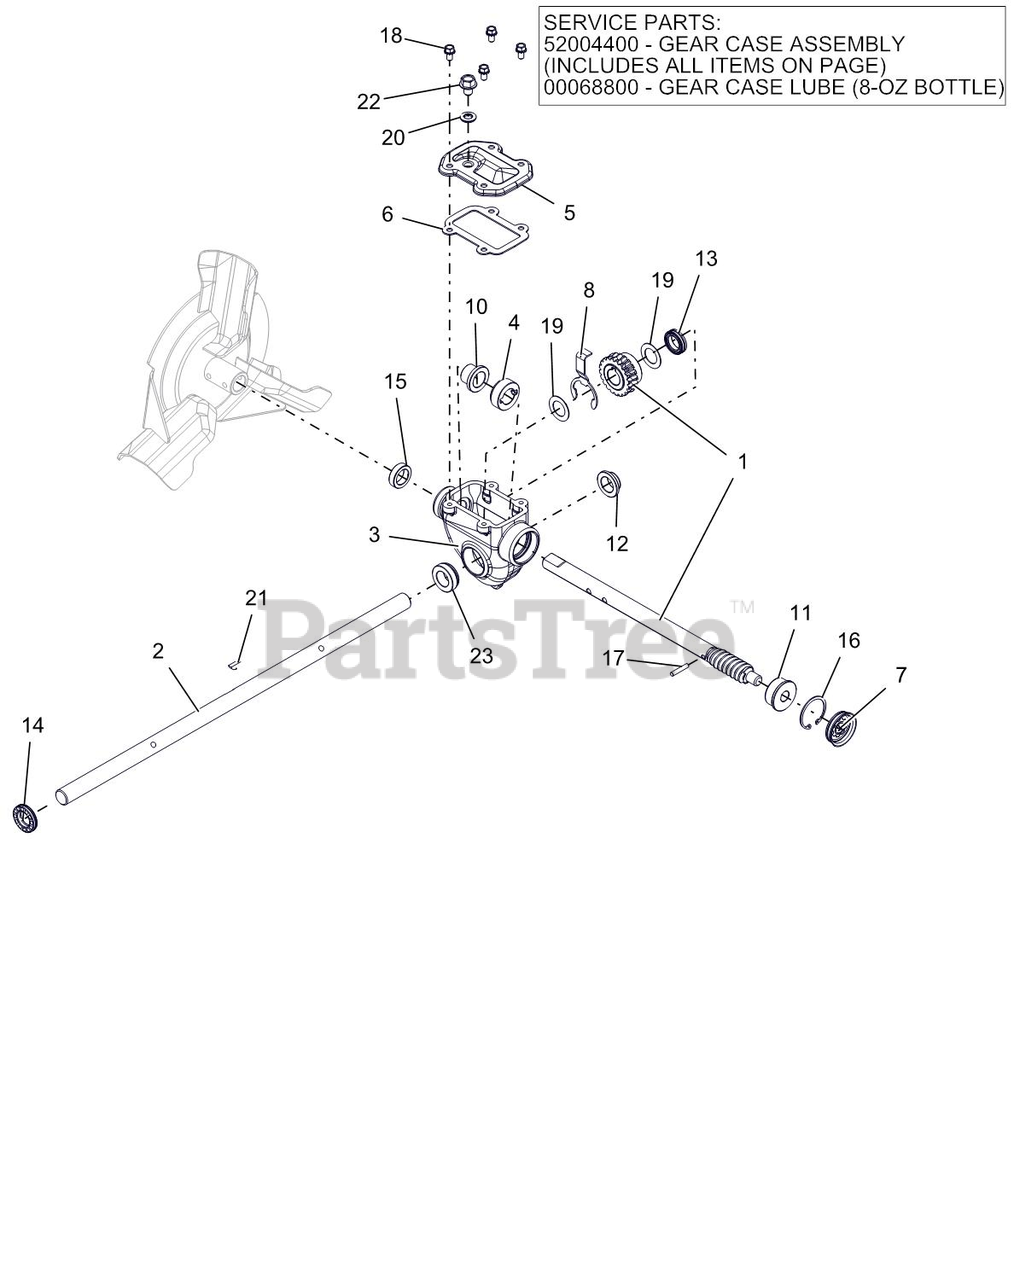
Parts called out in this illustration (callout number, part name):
1	SHAFT AND WORM GEAR ASSEMBLY
2	SHAFT, RAKE - 22" (.750 DIA)
3	GEARCASE, COMPACT MACHINED
4	THRUST COLLAR, .75" ID SLIPFIT
5	COVER, TOP - COMPACT
6	GASKET, TOP - COMPACT GEARCASE
7	COVER, GEAR CASE 1.50"
8	BUSHING RETAINER, COMPACT
10	BSHG-FLG .755X.878X.75X1.25
11	BSHG-FLG .503X1.303X.62X1.465
12	BSHG-FLG .755X.878X.424X1.25
13	SEAL-OIL .748X1.125X.312 TBC29
14	SEAL-OIL .748X1.300X.250 TBC29
15	SEAL-OIL .748X1.125X.312 TB2-H
16	RG-RTNG-INT 1.500X.050
17	PIN-STR .188X1.00 6150
18	BOLT, SEMS .25-20X.50 GR5 YWZC
19	WSHR-FL-STL .760X1.225X.032 YZ
20	WSHR-BND-SEAL .38X.75X.11 GALV
21	KEY-WDRF .19X.63 HRD #61
22	@SCR-ROLOK .38-16X.50 HWH YWZC
23	BSHG-FLG COMPACT, RIGHT
24	GEAR CASE, 24" IRON SM TOP-LD
25	ARIENS L3 LUBE, 8 OZ BOTTLE
